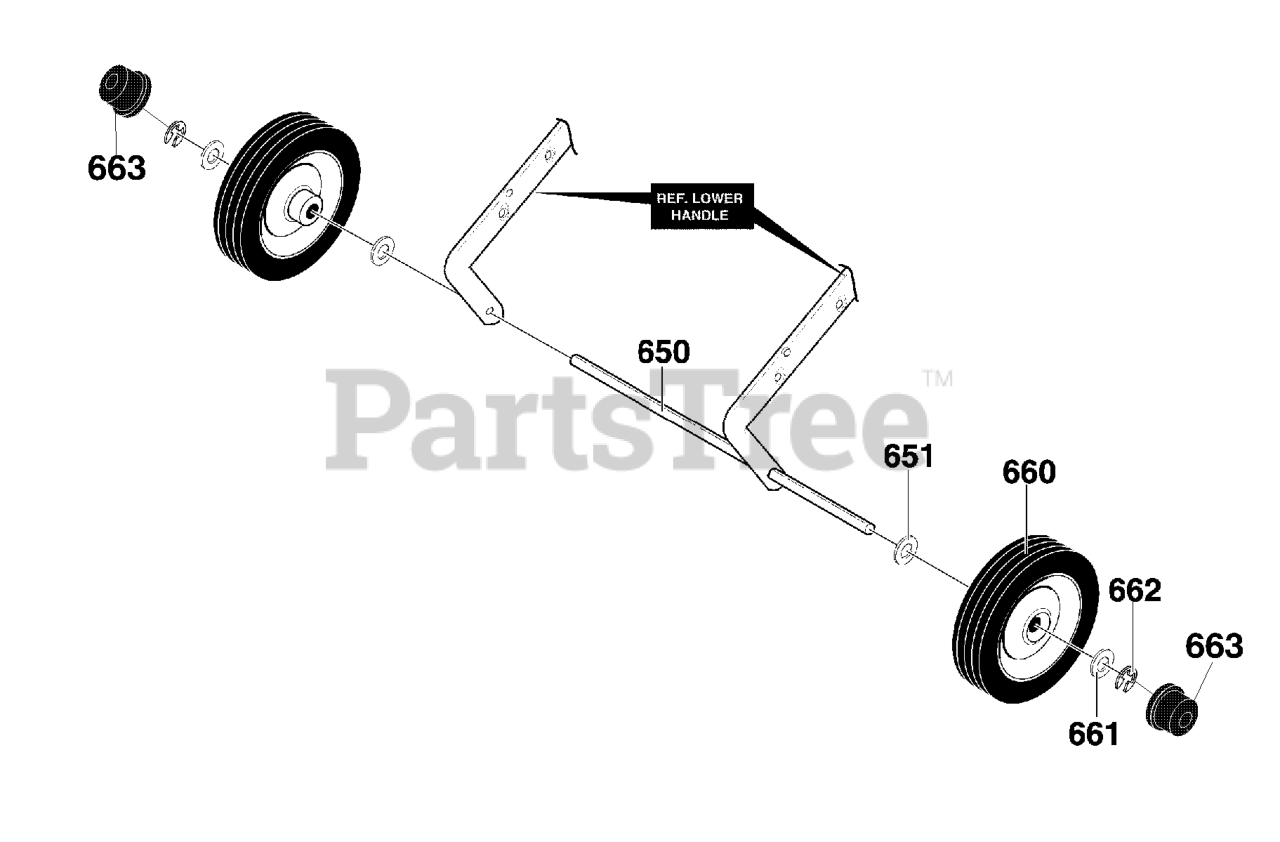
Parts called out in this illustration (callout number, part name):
650	AXLE SHAFT
651	WASHER, FLAT .391X1.00X1.25
660	TIRE & RIM
661	WASHER, FLAT .391X1.00X.125
662	RING, RET E
663	HUB CAP
